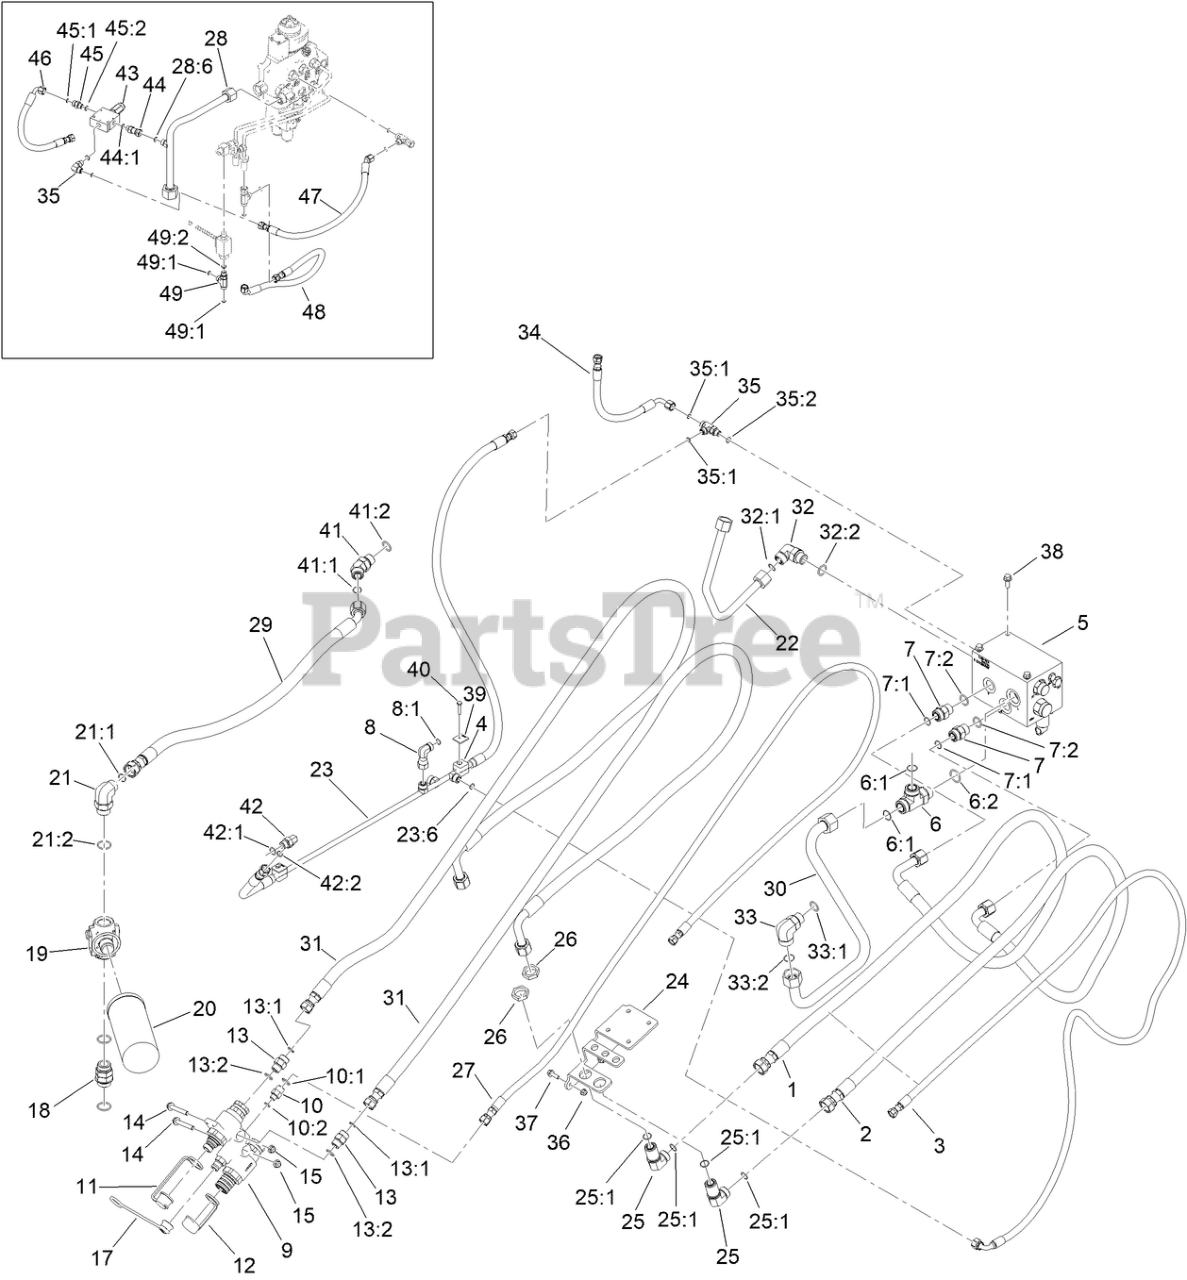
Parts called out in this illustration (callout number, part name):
1	HYD HOSE ASM
2	HYD HOSE ASM
3	HYD HOSE ASM
4	CLAMP-TUBE
5	AUX MANIFOLD ASM
6	FITTING-TEE
6:1	O-RING
6:2	O-RING
7	FITTING-HYD, STRAIGHT
7:1	O-RING
7:2	O-RING
8	FITTING-HYD
8:1	O-RING
9	MANIFOLD-QDC
10	FITTING-STRAIGHT
10:1	O-RING
10:2	O-RING
11	CAP-DUST, NIPPLE
12	CAP-DUST, COUPLER
13	FITTING-STRAIGHT
13:1	O-RING
13:2	O-RING
14	SCREW-HFH
15	NUT-HF, NI
17	CAP-DUST, NIPPLE
18	FITTING-STRAIGHT
19	HEAD-FILTER
20	ELEMENT-FILTER
21	FITTING-ELBOW 90
21:1	O-RING
21:2	O-RING
22	HYD TUBE ASM
23	HYD TUBE ASM
23:6	O-RING
24	MOUNT-CARRIER
25	FITTING-ELBOW 90
25:1	O-RING
26	NUT-BULKHEAD
27	HYD HOSE ASM
28	HYD TUBE ASM
28:6	O-RING
29	HYD HOSE ASM
30	HYDRAULIC TUBE ASM
31	HYD HOSE ASM
32	FITTING-ELBOW-90
32:1	O-RING
32:2	O-RING
33	FITTING-ELBOW 90
33:1	O-RING
33:2	O-RING
34	HYD HOSE ASM
35	FITTING-ELBOW, 90 DEG
35	FITTING-TEE
35:1	O-RING
35:2	O-RING
36	NUT-HF, NI
37	SCREW-HHF
38	SCREW-HHF
39	PLATE-CLAMP,TUBE
40	SCREW-HH
41	FITTING-45 DEG
41:1	O-RING
41:2	O-RING
42	FITTING-ELBOW, 90 DEG
42:1	O-RING
42:2	O-RING
43	VALVE-SEQUENCE
44	CONNECTOR-SWIVEL, STRAIGHT
44:1	O-RING
45	FITTING-STRAIGHT
45:1	O-RING
45:2	O-RING
46	HOSE ASM
47	HOSE-HYD
48	HOSE-HYD
49	FITTING-TEE
49:1	O-RING
49:2	O-RING
